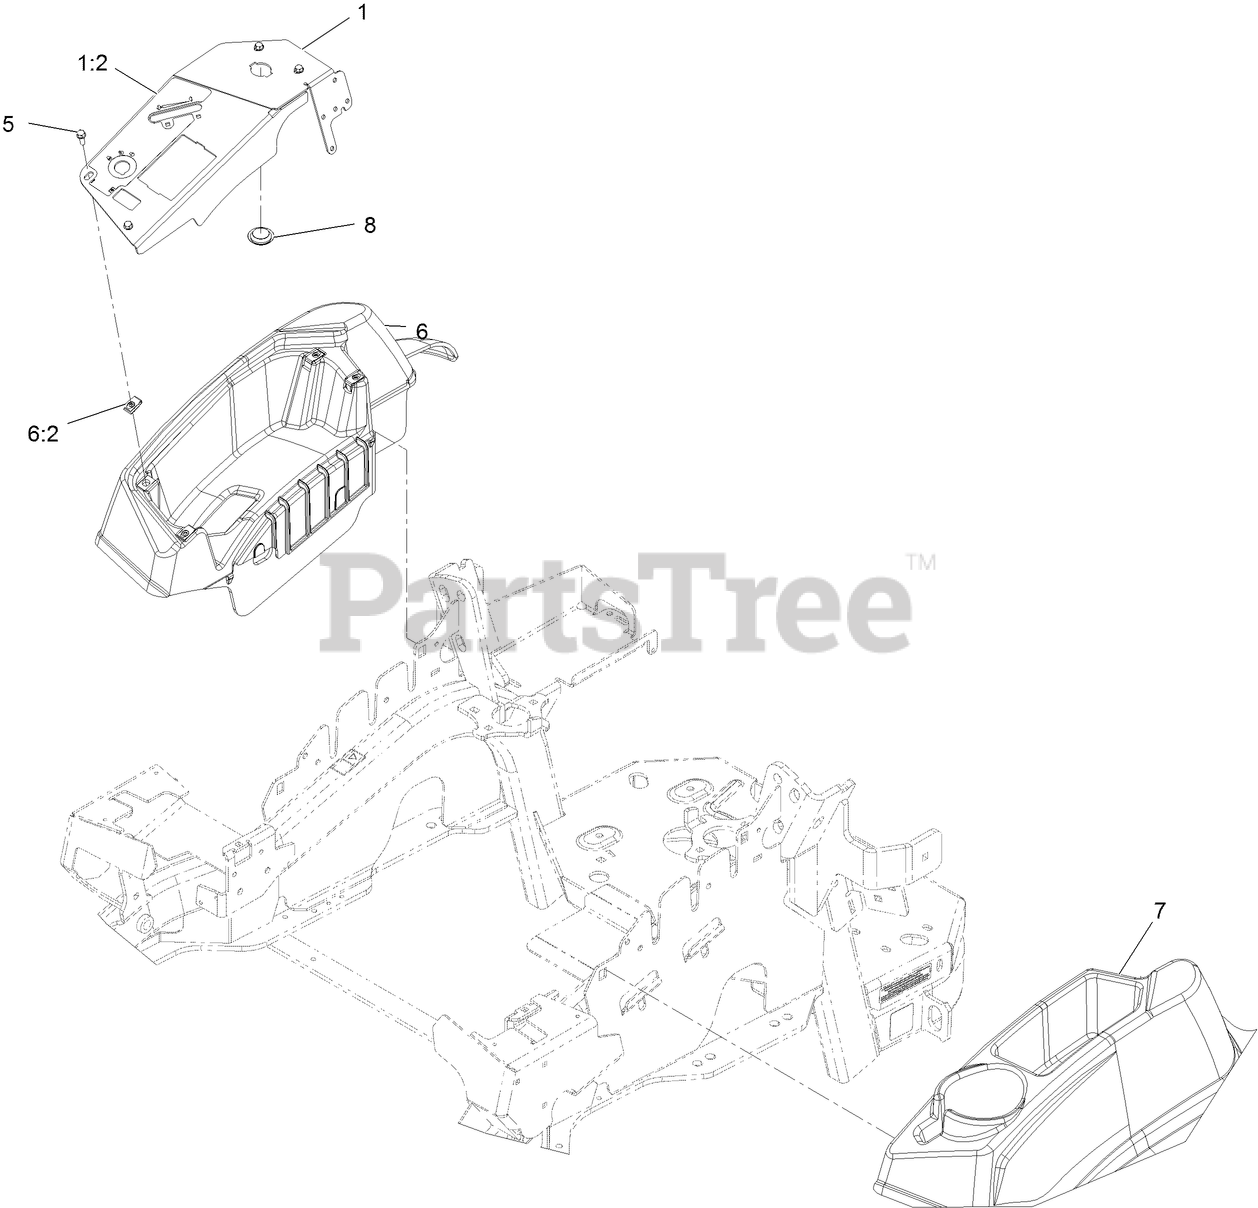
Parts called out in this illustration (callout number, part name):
1	PANEL-CONTROL W/DECAL SHM-EFI
1:2	DECAL-CONTROL PANEL-EFI
5	SCREW-HWH
6	CONSOLE,RH AS ASM
7	CONSOLE, LH AS
8	PLUG-PLASTIC
